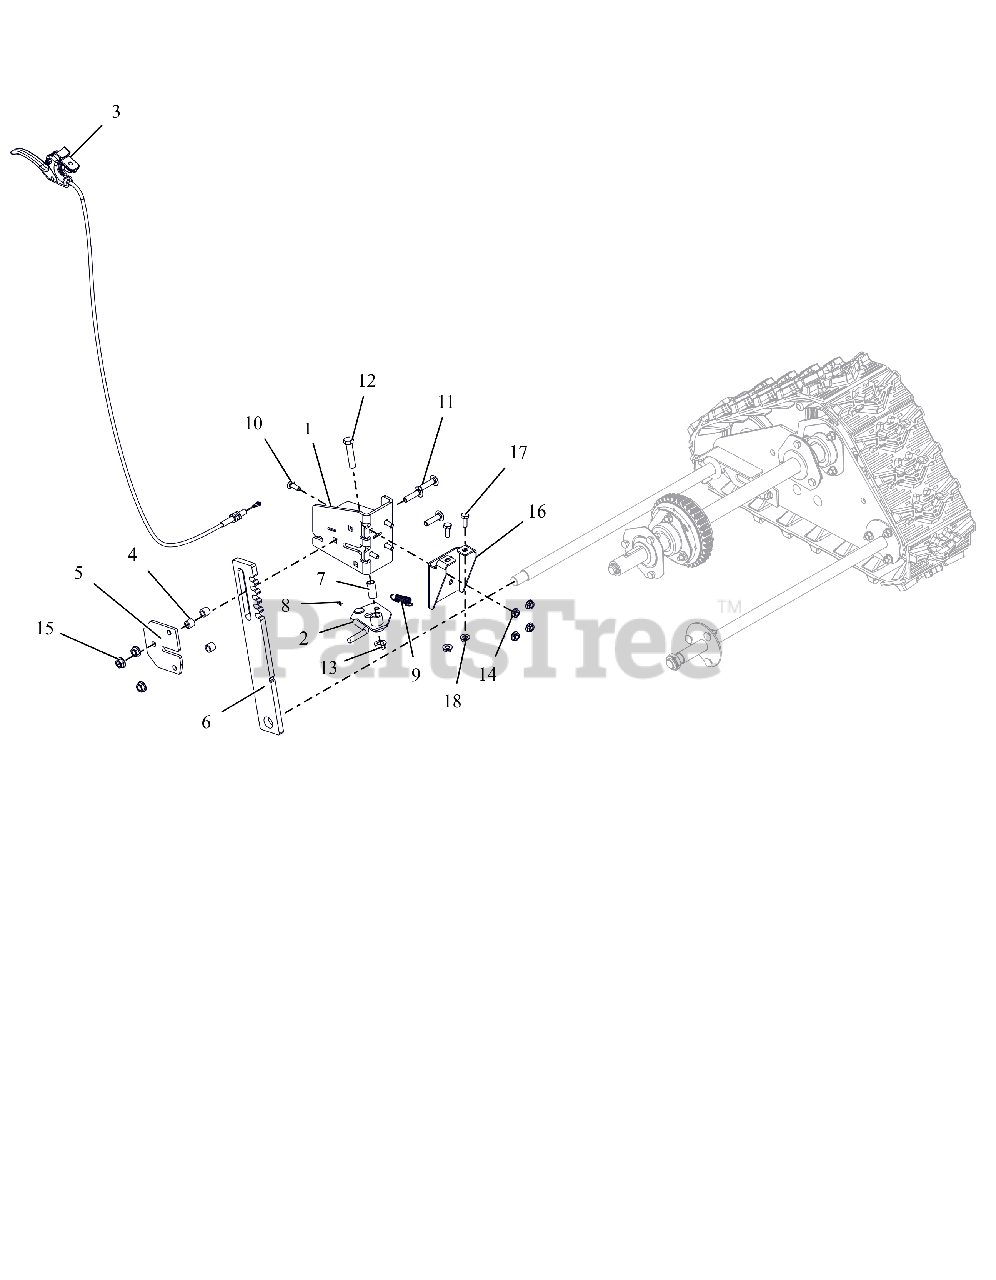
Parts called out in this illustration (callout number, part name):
1	BRACKET,HEIGHT ADJUSTER-DELUXE
2	LOCK,HEIGHT ADJUSTER TRIGGER
3	CABLE, TRACK REMOTE
4	SPACER .50 X .32 X .42
5	PLATE, HEIGHT ADJUSTER
6	STOP,HEIGHT ADJUSTER-DELUXE
7	BSHG-SLV .385X.500X1.045
8	PIN-HAIR INT .06X.18X.77
9	SPRING-EXT .047 X .438 X 1.85
10	@BLT-RDHDSQNK .25-20X.75 G5YZ
11	@BLT-RHDSHSQNK.31-18X1.25 G5YZ
12	@BLT-HEX .38-16X1.75 GR5 YWZC
13	NUT-LK-CTR-FLG .38-16 YWZC
14	@NUT-LK-CTR-FLG .25-20 YWZC
15	@NUT-LK-TOP-FLG .31-18 YWZC
16	BRACKET, REINFORCEMENT
17	@BLT-HEX .25-20X.75 GR5 YWZC
18	@NUT-LK-CTR-FLG .25-20 YWZC
